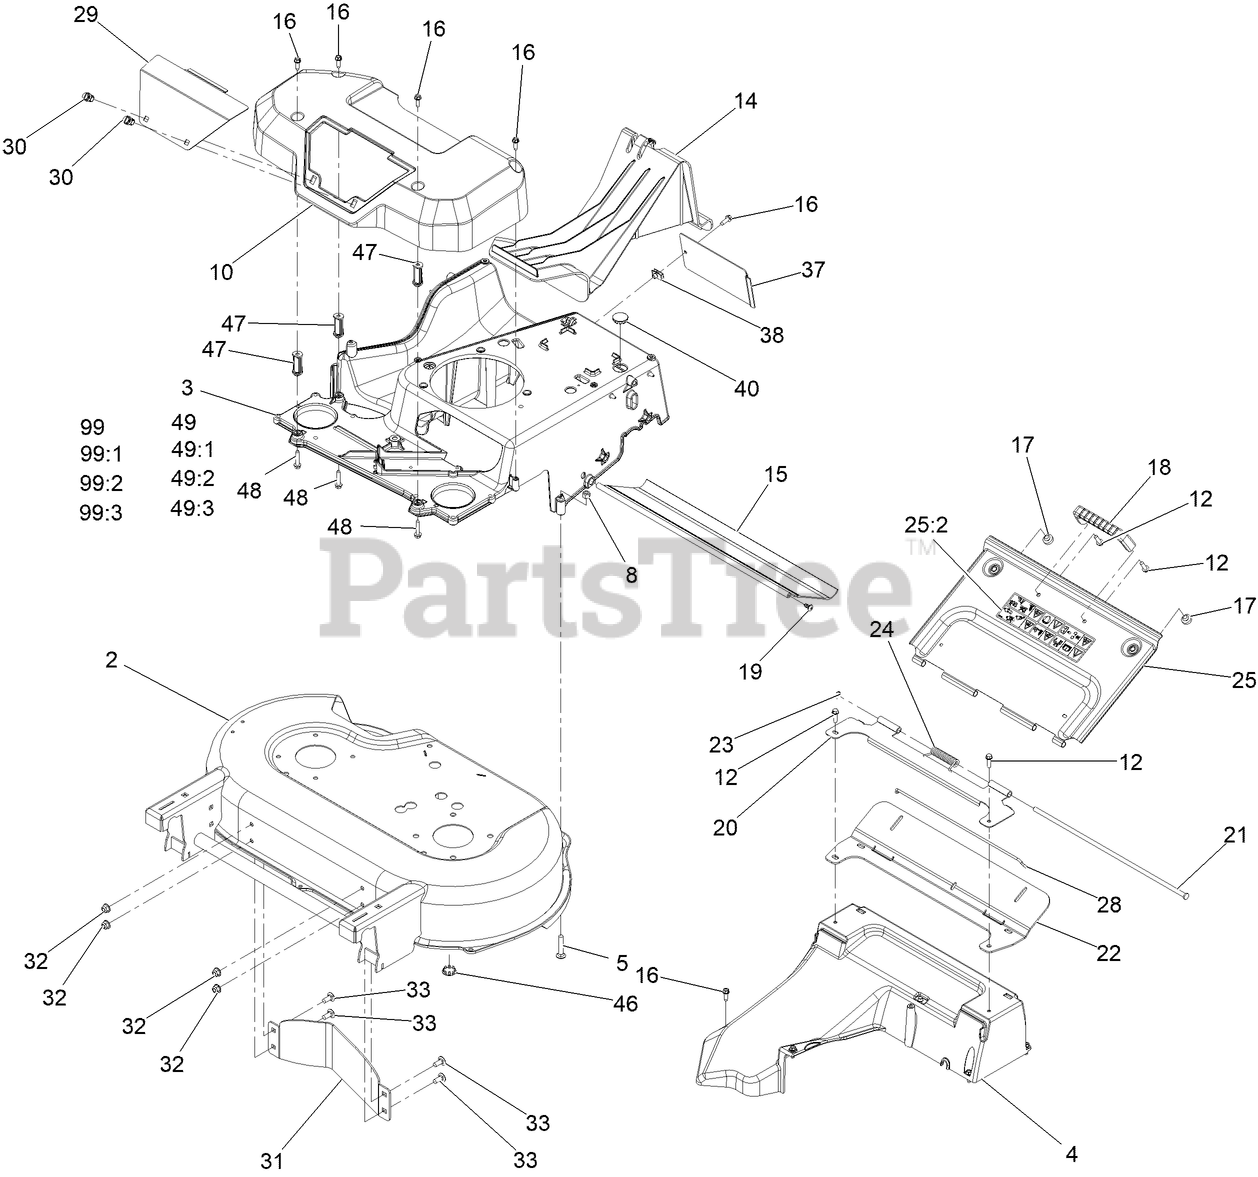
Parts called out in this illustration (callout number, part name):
2	HOUSING ASM
5	BOLT-CAR
8	NUT-LOCK, NI
10	COVER-BELT
12	SCREW-HWH
14	PLUG-MULCH
15	SHIELD-TRAILING
16	SCREW-HWHTF
18	HANDLE-DOOR
19	SCREW-PTH
20	BRACKET-HINGE
21	PIN-HINGE
22	SEAL-DOOR
23	RING-RETAINING
24	SPRING-TORSION, COVER
25	REAR DOOR ASM
25:2	DECAL-WARNING
28	CLIP-SEAL
29	PANEL-ACCESS
30	FASTENER
31	BAFFLE-CONTROL
32	NUT-HF, NI
33	SCREW-HSBH
37	Cover-Frame
40	PLUG-BUTTON
46	PLUG-BUTTON
47	SPACER-FRAME, 30 IN.
48	SCREW-HWH THD ROLL
49	FRAME-PLATE KIT
49:1	PLATE-FRAME, ASM
49:2	SCREW-CARR
49:3	NUT-LOCK, NI
99	FRAME PLATE KIT
99:1	PLATE-FRAME
99:2	SCREW-CARR
99:3	NUT-LOCK, NI
